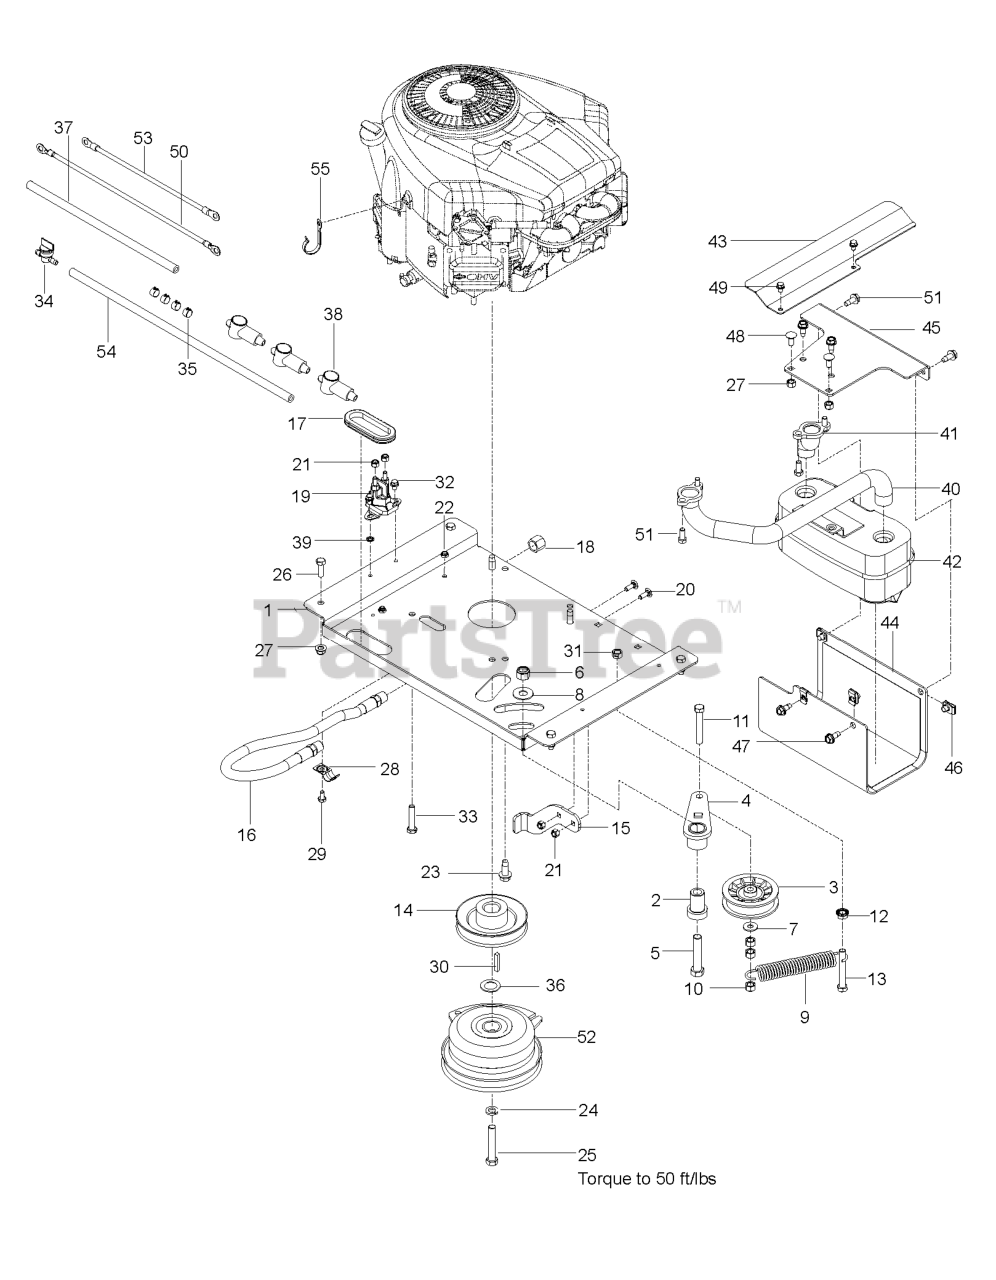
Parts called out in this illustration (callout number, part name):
1	PLATE, ENGINE
2	IDLER SPINDLE
3	PULLEY, IDLER RAKE & ZTR
4	RP.IDLER ARM WELDMENT
5	HEX SCREW 1/2-13 X 2.5" GR 5
6	NUT 1/2-13 HEX NYLOC ZD
7	WASHER 5/16 FLAT
8	WASHER 1/2 FLAT
10	NUT 3/8-16 NYLOC
11	HCS 3/8-16 X 2-1/2 TPBLT
12	NUT 3/8C WHIZ
13	SCREW 3/8C X 2 3/4 HEX CAP
15	TIE DOWN, CLUTCH
16	DRAIN, OIL
20	RHSNB 1/4C X 3/4
21	NUT.1/4-20.HEX.NYLOC.ZD
22	JAM NUT 1/4C (2 2 PW01)
23	HHFS 3/8-16 X 1.0 THD FORMING
24	WASHER 7/16 LOCK
25	BOLT 7/16F X 2 1/2
26	HCS 5/16C X 1
27	5/16-18 NYLOC FLANGE NUT
29	HCS 1/4-20.
30	KEY, 1/4 SQ X 1 1/4
31	NUT 3/8C CENTERBLOCK
32	HWST 1/4C X 3/8
33	HCS 5/16C X 1 3/4
34	FUEL VALVE
35	HOSE CLAMP
36	WASHER, 1.025 ID X 1.64
37	FUEL LINE 13"
39	WASHER 1/4 INT TOOTH
40	MANIFOLD, FT
41	MANIFOLD, RR
42	MUFFLER ASM TWIN
43	SHIELD, HEAT
44	GUARD, MUFFLER
45	MOUNT MUFFLER BLACK
46	U-CLIP 5/16-18 NUT RETAINER
47	BOLT 5/16-18 X 3/4
48	BOLT 5/16C X 3/4" CARRIAGE
49	HWST 1/4C X 3/8
50	BATTERY GROUND CABLE
51	HCS 5/16C X 3/4
52	CLUTCH, 125 FT/LB
53	CABLE, POSITIVE
54	FUEL LINE 30"
